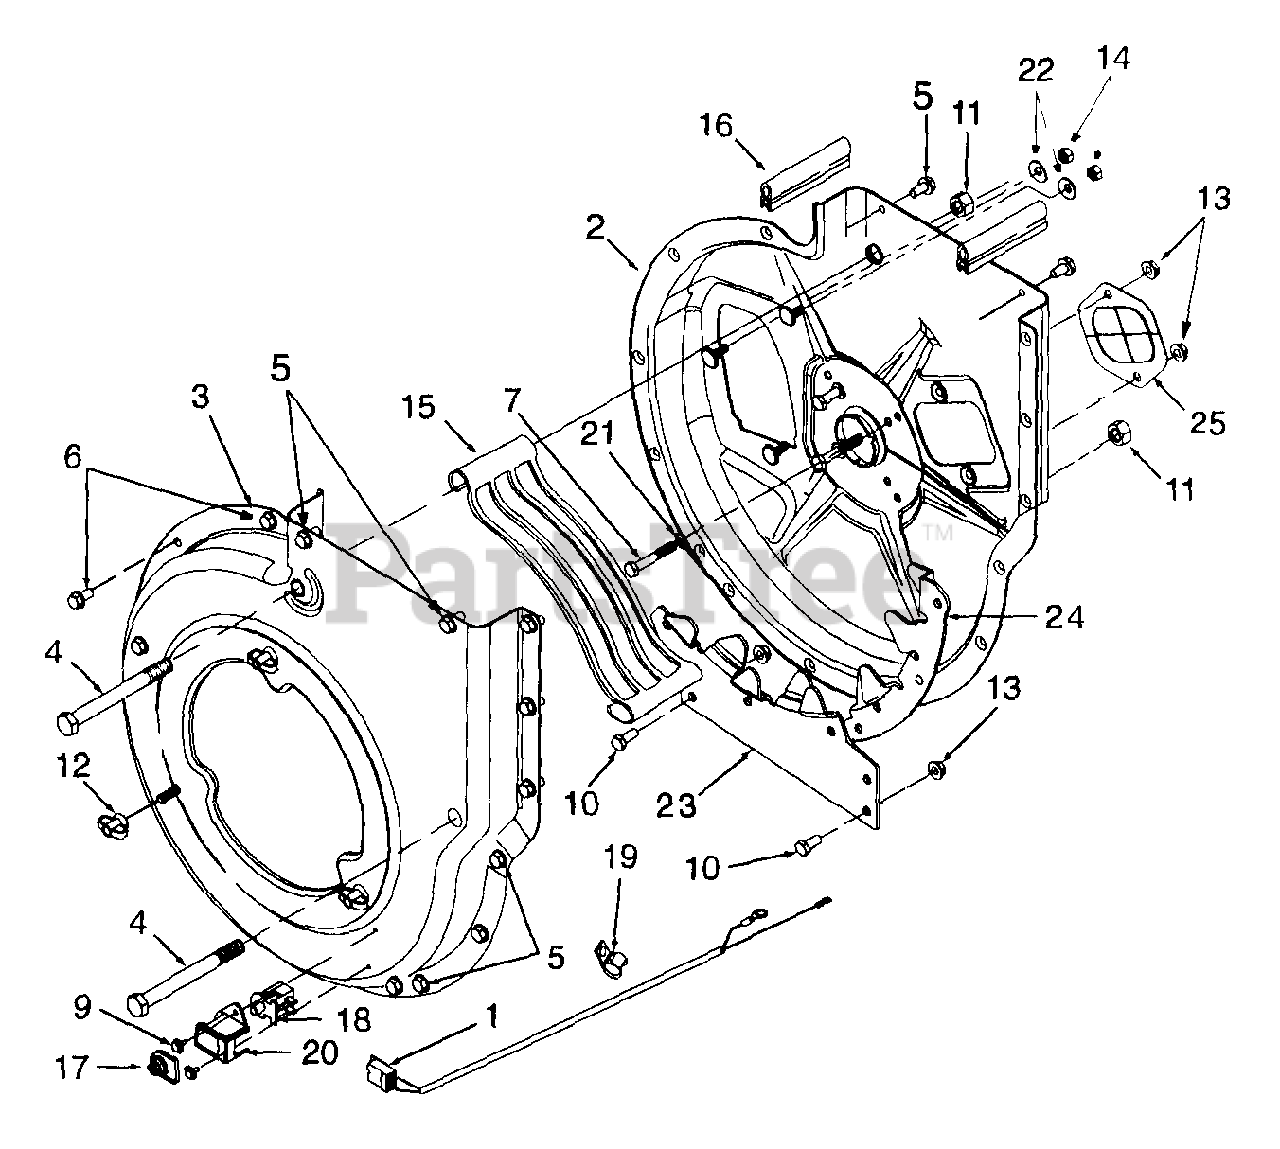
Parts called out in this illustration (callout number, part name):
1	Harness, Wire
2	Housing Ass'y, Inner Flail
3	Housing Ass'y, Outer Flail
4	Screw, Hex Cap, 1/2-13 x 5.0
5	Screw, Hex Wash Hd Tapp 5/16-18 x .62
6	Screw, Hex Wash Hd Tapp 5/16-18 x .50
7	Screw, Hex Cap, 5/16-24 x 2 GR5
9	Screw, Hex Wash Hd Tapp #10-16 x .38
10	Screw, Hex Cap, 5/16-18 x .75 GR5
11	Nut, Hex Center Lock, 1/2-13
12	Knob, 5/16-18
13	Nut, Hex Flange Lock, 5/16-18
14	Nut, Hex, 5/16-18
15	Screen, Discharge
16	Rubber Seal
17	Cover, Switch
18	Switch, Snap Mount
19	Clamp
20	Cover, Safety Switch Mtg.
21	Washer, Lock, 5/16
22	Washer, Bell, .345 x .88 x .06
23	Blade, Lower Shredder
24	Blade, Upper Shredder
